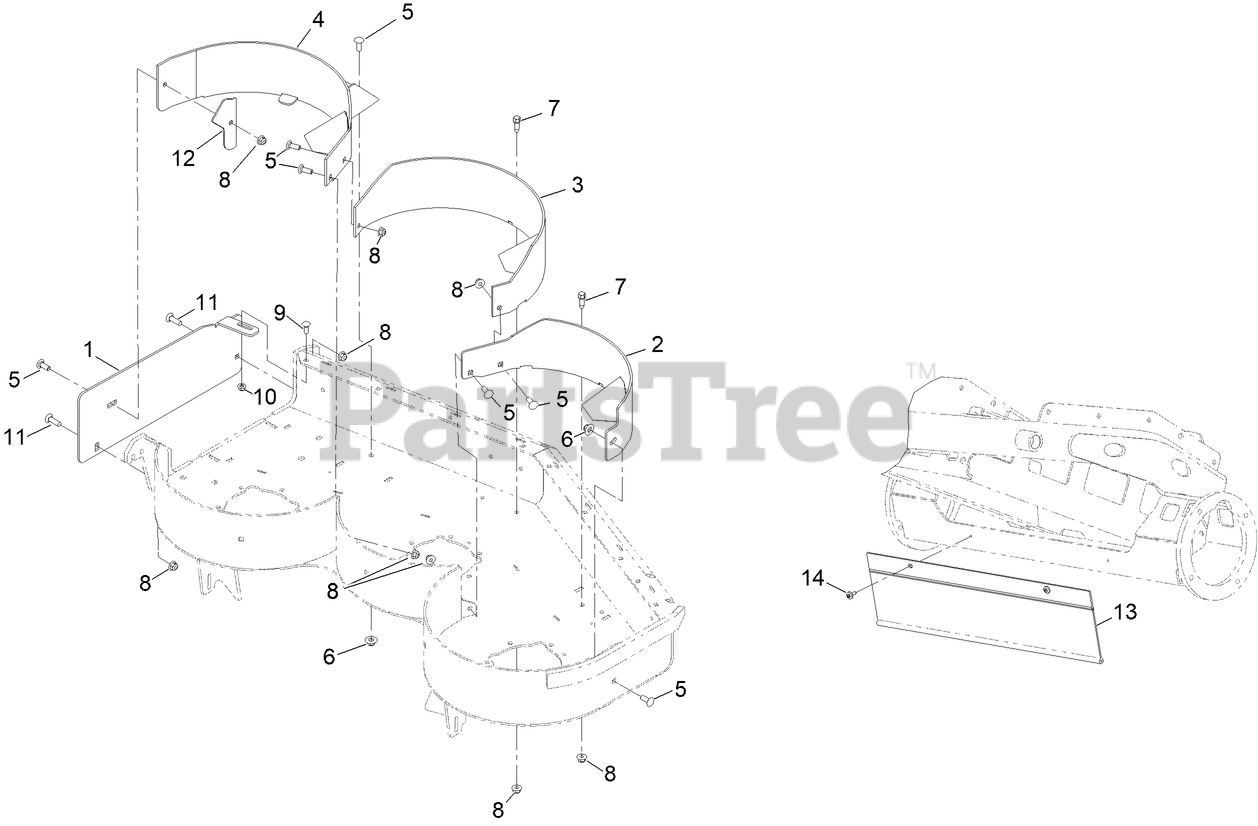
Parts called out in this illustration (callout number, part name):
1	PLATE-COVER, DISCHARGE
2	BAFFLE-LH
3	BAFFLE-CENTER
4	RH BAFFLE ASM
5	SCREW-CARR
6	NUT-FLANGE, NI
8	NUT-HF, NI
9	SCREW-CARR
10	NUT-HF, NI
11	SCREW-CARR
12	PLATE-SIDE COVER
13	SHIELD-TRAILING
14	SCREW-SHOULDER
